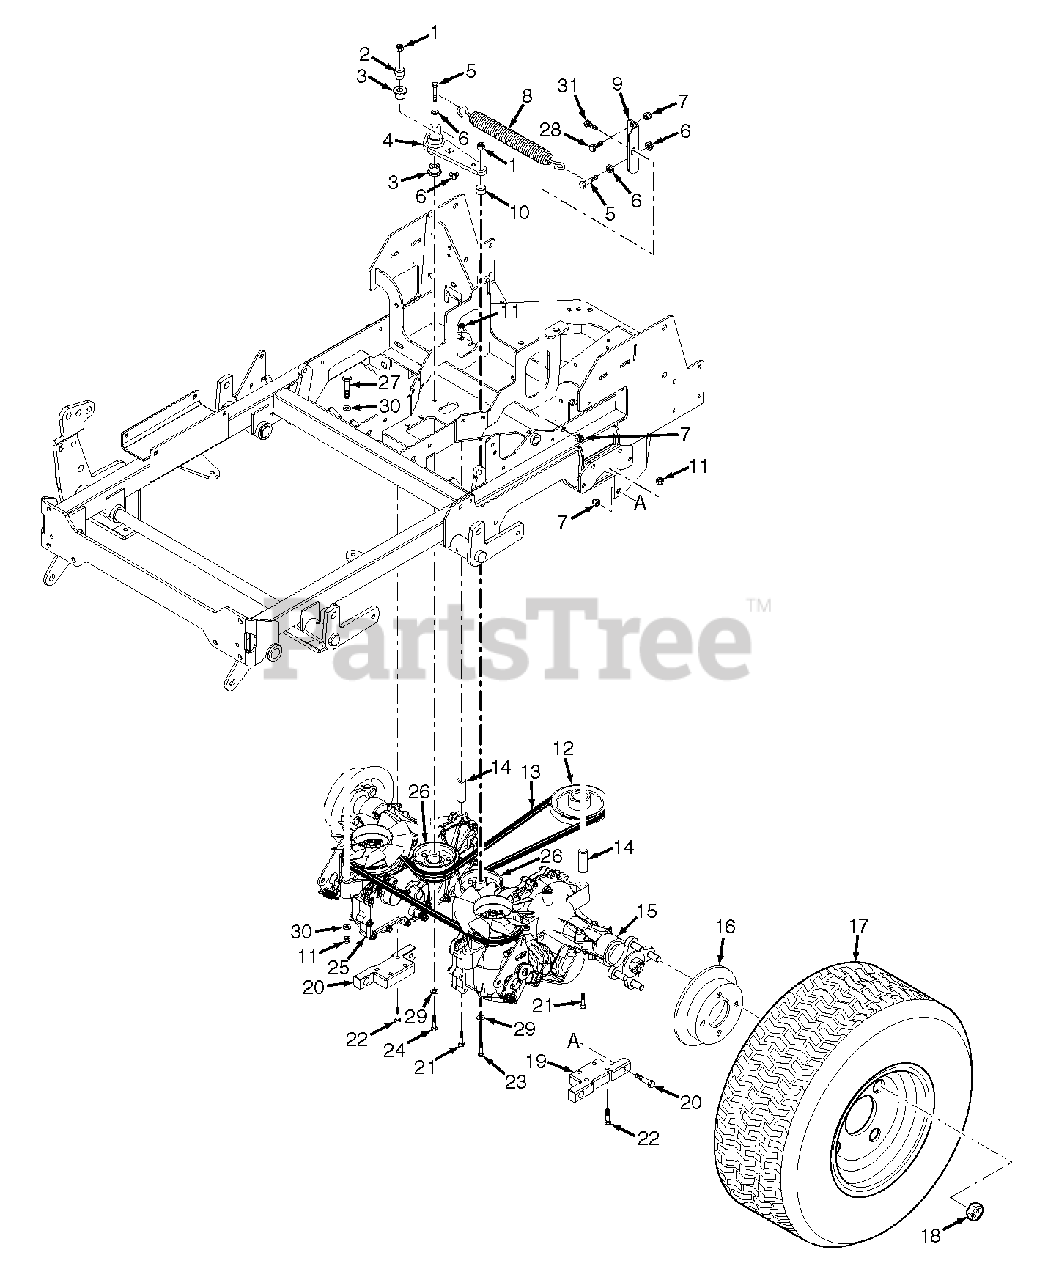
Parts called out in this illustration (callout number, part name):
1	Nut, Elastic Stop 3/8-16
2	Shaft, Pivot Idler Arm
3	Bearing
4	Idler Arm Assembly
5	Bolt, Hex Head 3/8-16 x 1-1/2"
6	Nut, Serrated Flange 3/8-16
7	Nut, Elastic Stop 3/8-16
8	Spring, Pump Drive
9	Anchor Bracket, Pump Spring
10	Spacer
11	Nut, Elastic Stop 5/16-18
12	Pulley, 5" Dia. - 1.125" Bore
13	Belt, Pump Drive
14	Spacer, Axle
15	Transaxle, LH
16	Spacer, Axle
17	Wheel Assembly, 23 x 9.5-12 (48)
17	Rim (48)
17	Tire, 23 x 9.5-12
17	Wheel Assembly, 23 x 9.5-12 (52)
17	Rim (52)
18	Wheel Nut, 1/2-20
19	Mount, Pusharm
20	Bolt, Hex Head 5/8-11 x 2-1/2"
21	Bolt, Hex Head 5/16-18 x 4-3/4"
22	Bolt, Hex Head 5/16-18 x 4"
23	Bolt, Hex Head 3/8-16 x 3-1/4"
24	Bolt, Hex Head 3/8-16 x 4-1/4"
25	Transaxle, RH
26	Pulley, 3-1/2" Idler
27	Bolt, Hex Head 5/16-18 x 2-1/4"
28	Bolt, Hex Head 3/8-16 x 1"
29	Flatwasher, 3/8-.391 x .938 x .105 HD
30	Flatwasher, 5/16-.375 x .875 x .083
31	Bolt, Hex Head 3/8-16 x 1-1/4"
